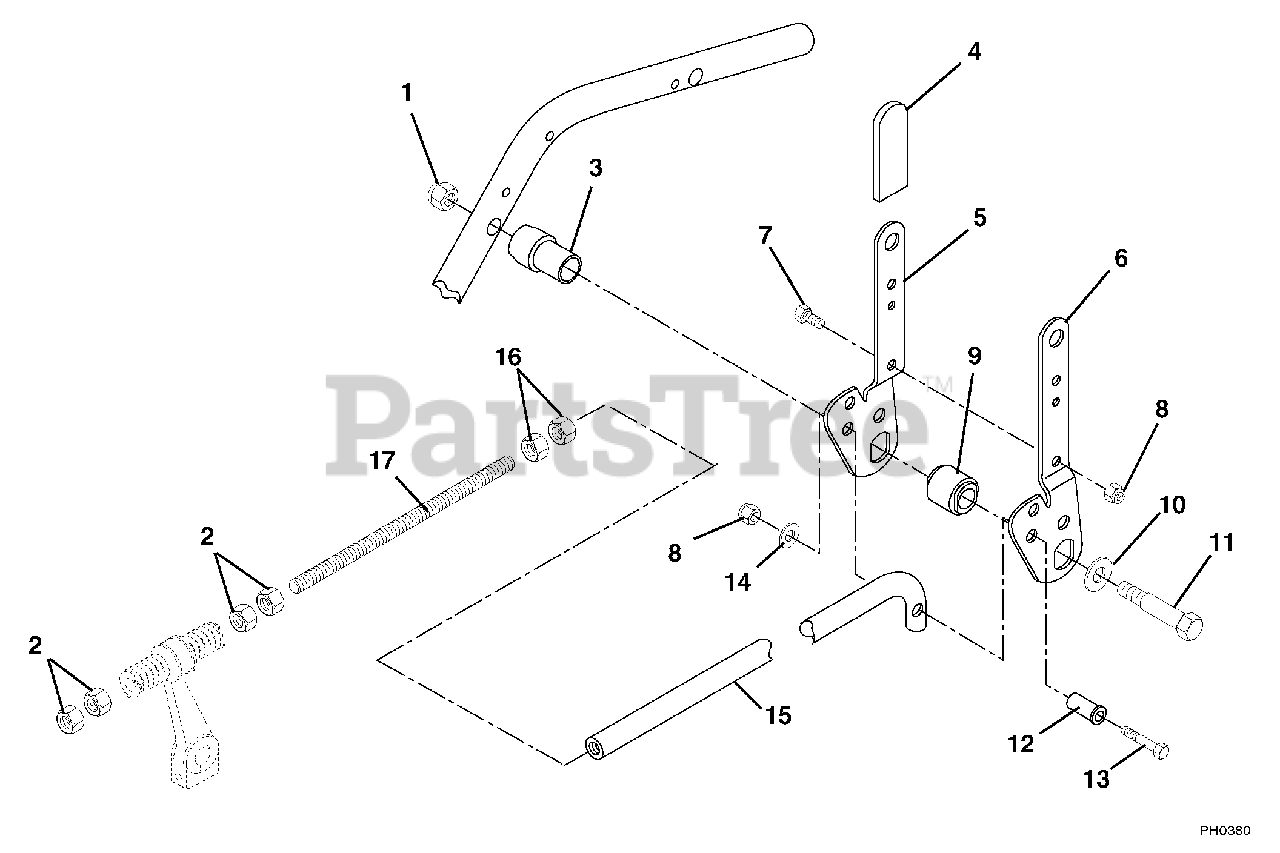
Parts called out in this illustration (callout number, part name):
1	Nut-Locking-Center .38-16
2	Nut-Jam .38-16
3	Pivot-Hand Lever Left Hand
4	Grip-Handle
5	Handle-Control Right Hand
6	Handle-Control Left Hand
7	Bolt-Hex .25-20 x .62
8	Nut-Locking-Center .250-20 Grade 2
9	Bushing Flange .751 x 1.13 x 1.07
10	Washer-Flat-Steel .531 x 1.062 x .095
11	Bolt-Hex .38-16 x 3.75
12	Bushing-Flange .257 x .38 x 1.080
13	Bolt-Hex .25-20 x 1.50 Grade 5
14	Washer-Flat-Steel .281 x .620 x .065
15	Rod-Control Hi-Lo
16	Nut-Hex .375-16 Grade 2
17	Rod-Extension
